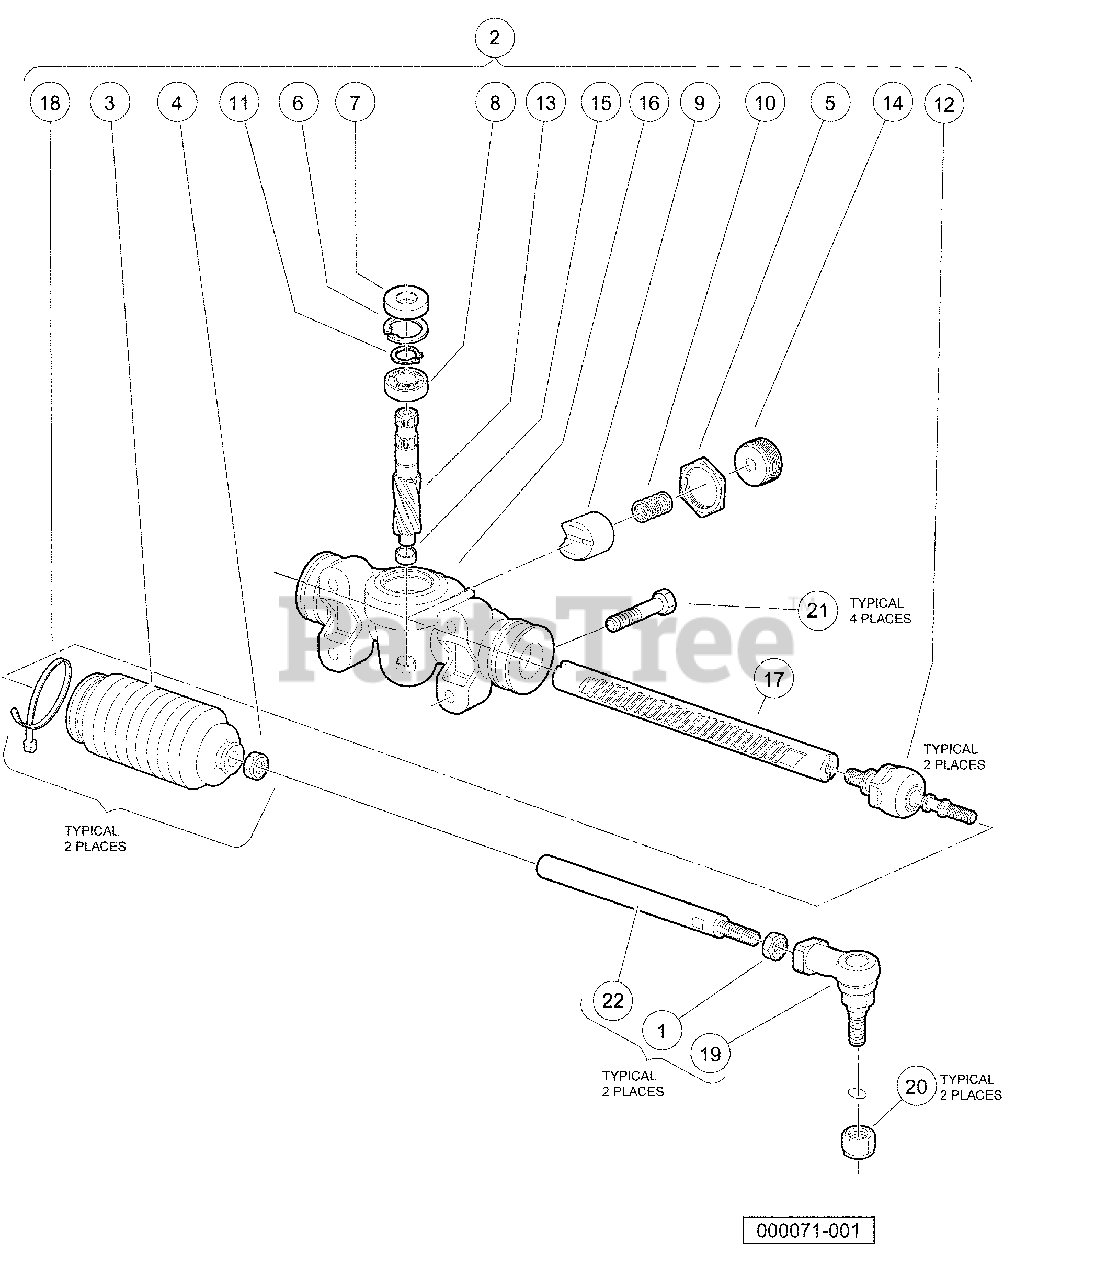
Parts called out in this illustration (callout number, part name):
1	Nut, 12mm Hex
2	Steering Rack
3	Bellows, Long
4	Nut, 12mm Hex
5	Rack Screw Locknut
7	Seal, Steering Pinion Dust
8	Bearing, Ball
9	Support Yoke
10	Rack Guide Pressure Spring
11	Ring, Stop, C-Type
12	Inner Ball Joint Asm
13	Pinion, Steering
14	Bearing, Lower Pinion
15	Screw, Rack Guide
16	Housing, Steering Gear
17	Rack, Steering
18	Tie Wrap, 8" Nylon
19	End, Tie Rod M12 X 1.25
20	Locknut, M12-1.25 Nylon
21	Bolt, Flange Head, M10x 1.5 X 40 with Loctite
22	Link, Drag, Wt
